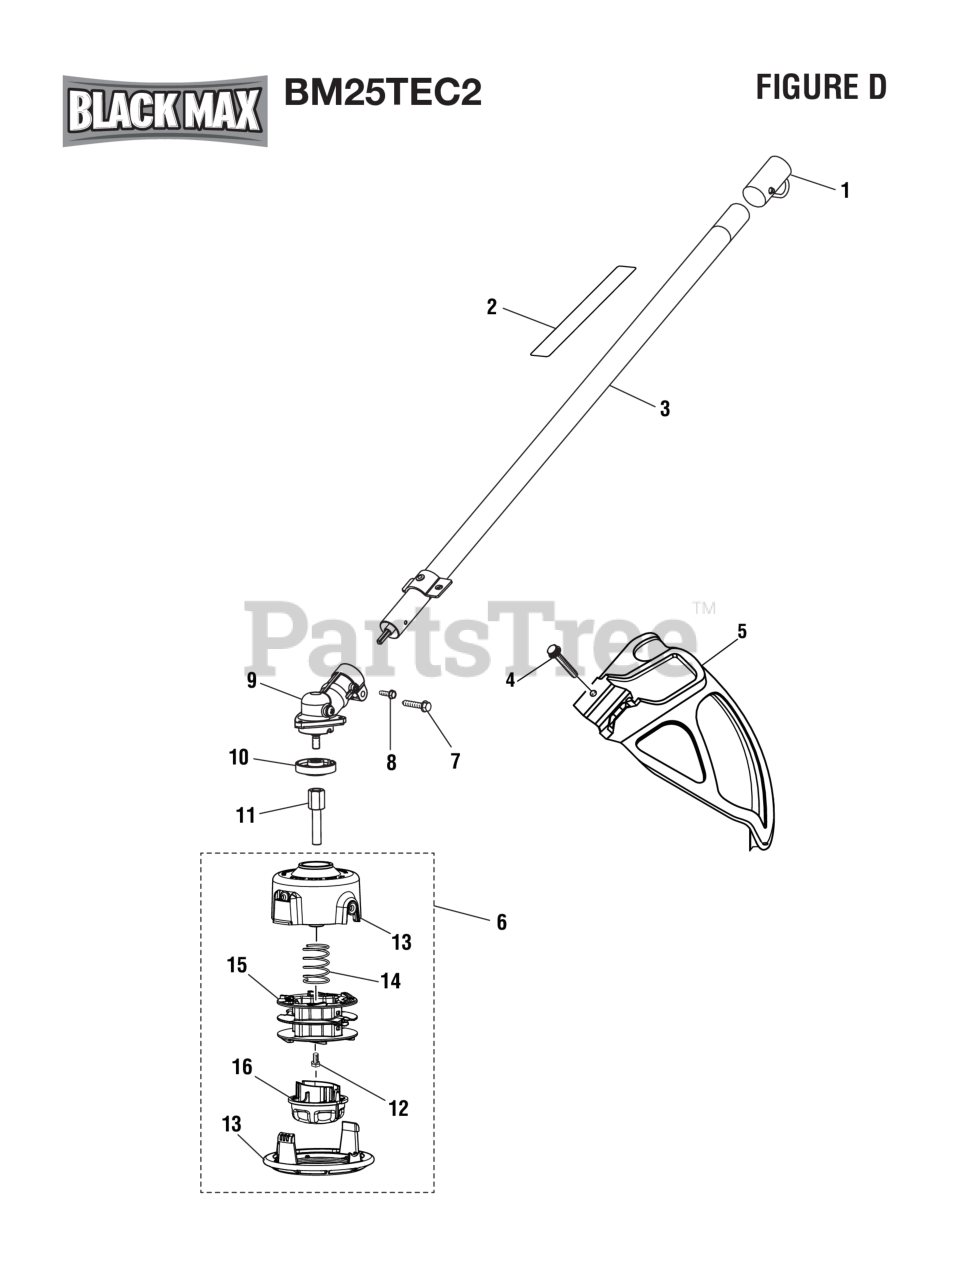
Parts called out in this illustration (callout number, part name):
1	Hanger Cap
2	Warning Icon Label
3	Straight Shaft Assembly
4	SCREW (#1/4-20 X 1-1/4 in. HEX WASHER HD.)
5	Grass Deflector Assembly
6	Trimmer Head Assembly (.095)
7	Screw (1/4-20 x 1-1/4 in., Hex Washer Hd. S.T.)
8	Screw w/Washer (10-24 x 5/8 in., Hex Hd. T.F.)
9	Gear Head Assembly
10	FLANGED WASHER
11	Trimmer Head Shaft Adaptor
12	Screw (5/16 x 1/2 in., Left Hand)
13	Stringhead Housing
14	Compression Spring
15	Spool w/ Line (.095)
16	Bump Knob
